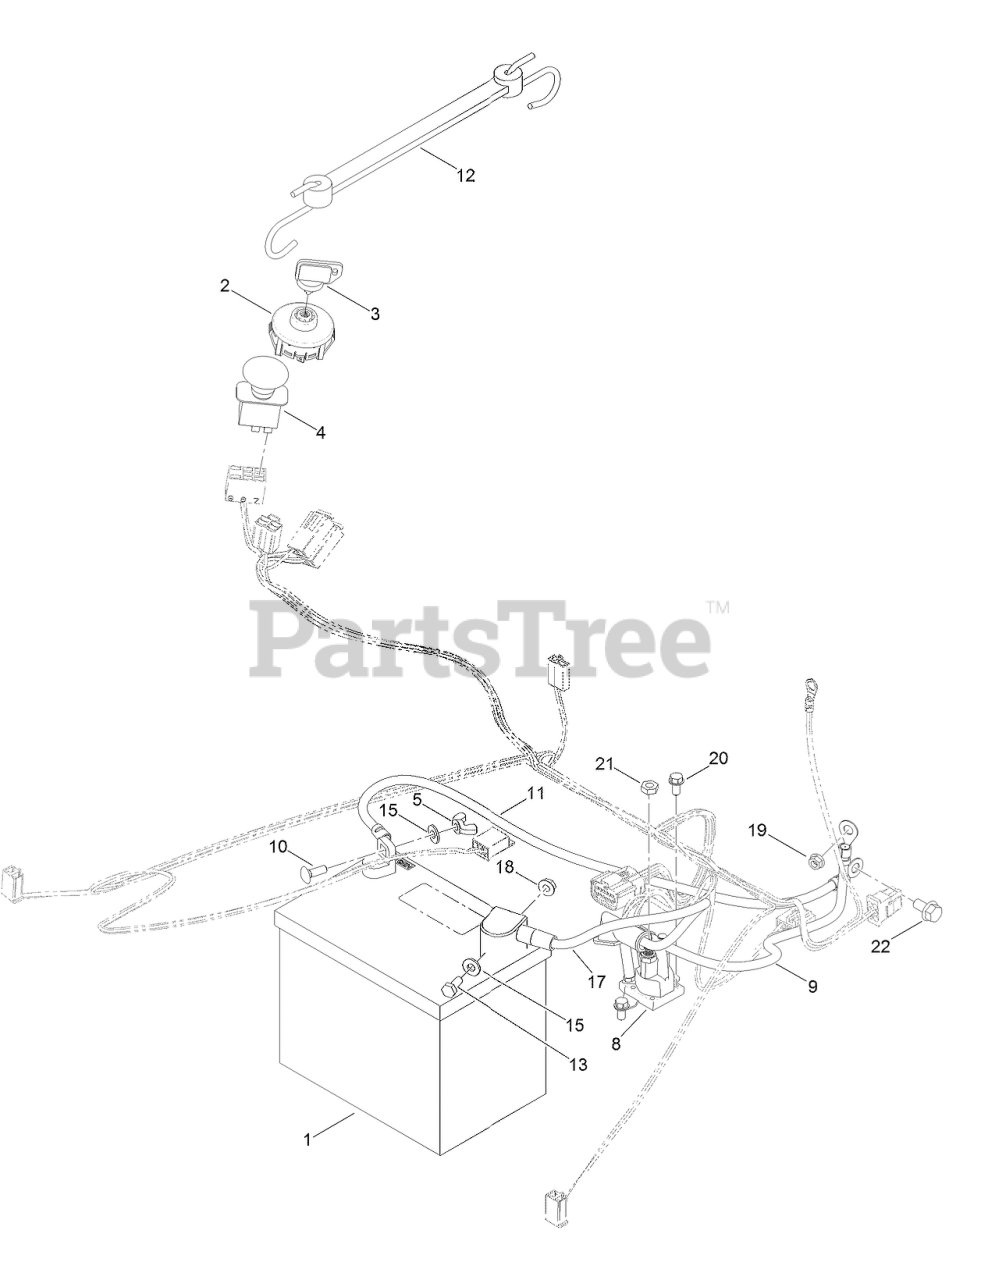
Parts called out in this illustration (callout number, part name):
1	BATTERY
2	SWITCH-IGNITION
3	KEY-IGNITION
4	SWITCH-PTO
5	NUT-WING
8	SOLENOID
9	CABLE-BATTERY, POSITIVE
10	BOLT-CARR
11	CABLE-BATTERY, BLACK
12	HOLDDOWN-BATTERY
13	SCREW-HH
15	WASHER-FLAT
17	CABLE-BATTERY, RED
18	NUT-HF
19	NUT-HF
20	SCREW-HWH
21	NUT-JAM
22	SCREW-HHF
